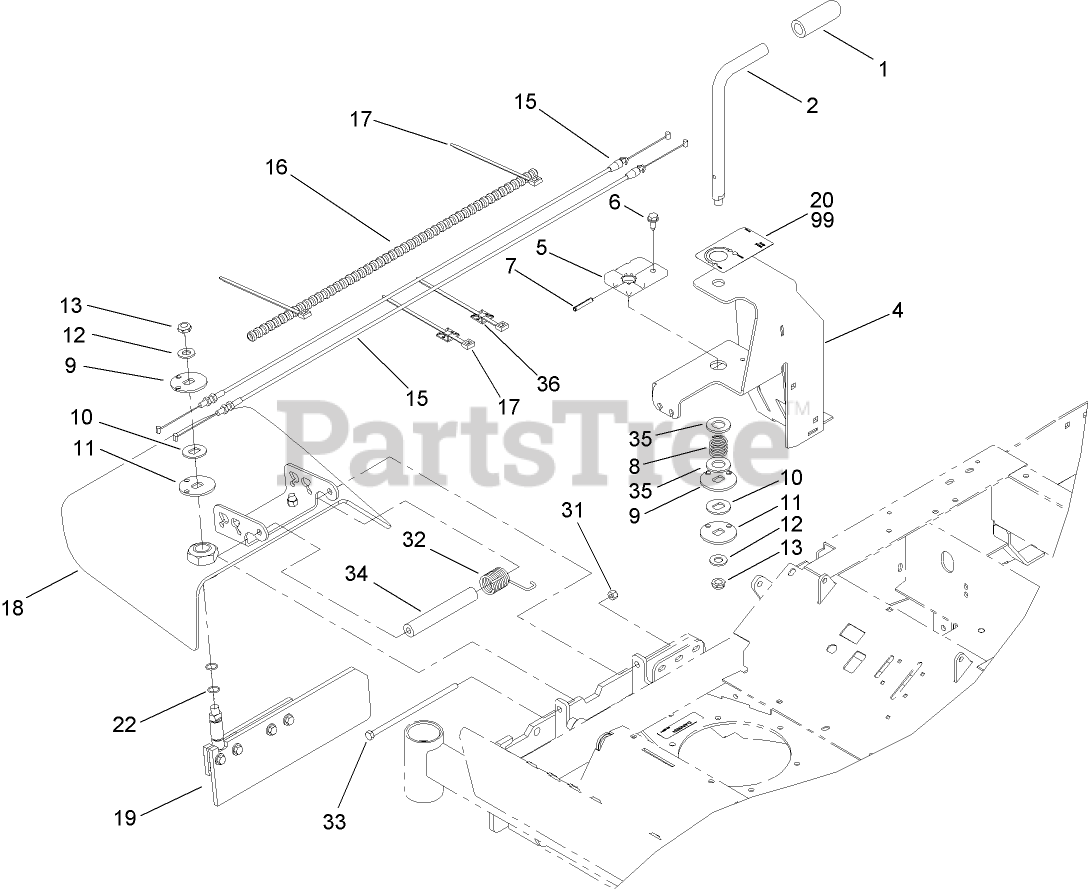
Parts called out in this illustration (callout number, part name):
2	HANDLE
4	BRACKET-MOUNT
5	BLOCK-DETENT
6	SCREW-HWHTF
7	PIN-ROLL
8	SPRING-COMPRESSION
9	PULLEY-TOP
10	PULLEY-MIDDLE
11	PULLEY-BOTTOM
12	WASHER-FLAT
13	NUT-LOCK, NI
16	TUBE-CONVOLUTED
17	TIE-CABLE
18	RUBBER DEFLECTOR ASM
19	DOOR ASM
20	DECAL-GATE, CHUTE
22	O-RING
31	NUT-LOCK, NI
32	SPRING-TORSION
33	SCREW-HH
34	SPACER
35	WASHER-FLAT
36	MOUNT-TIE, CABLE
99	DECAL-GATE, CHUTE (CE)
